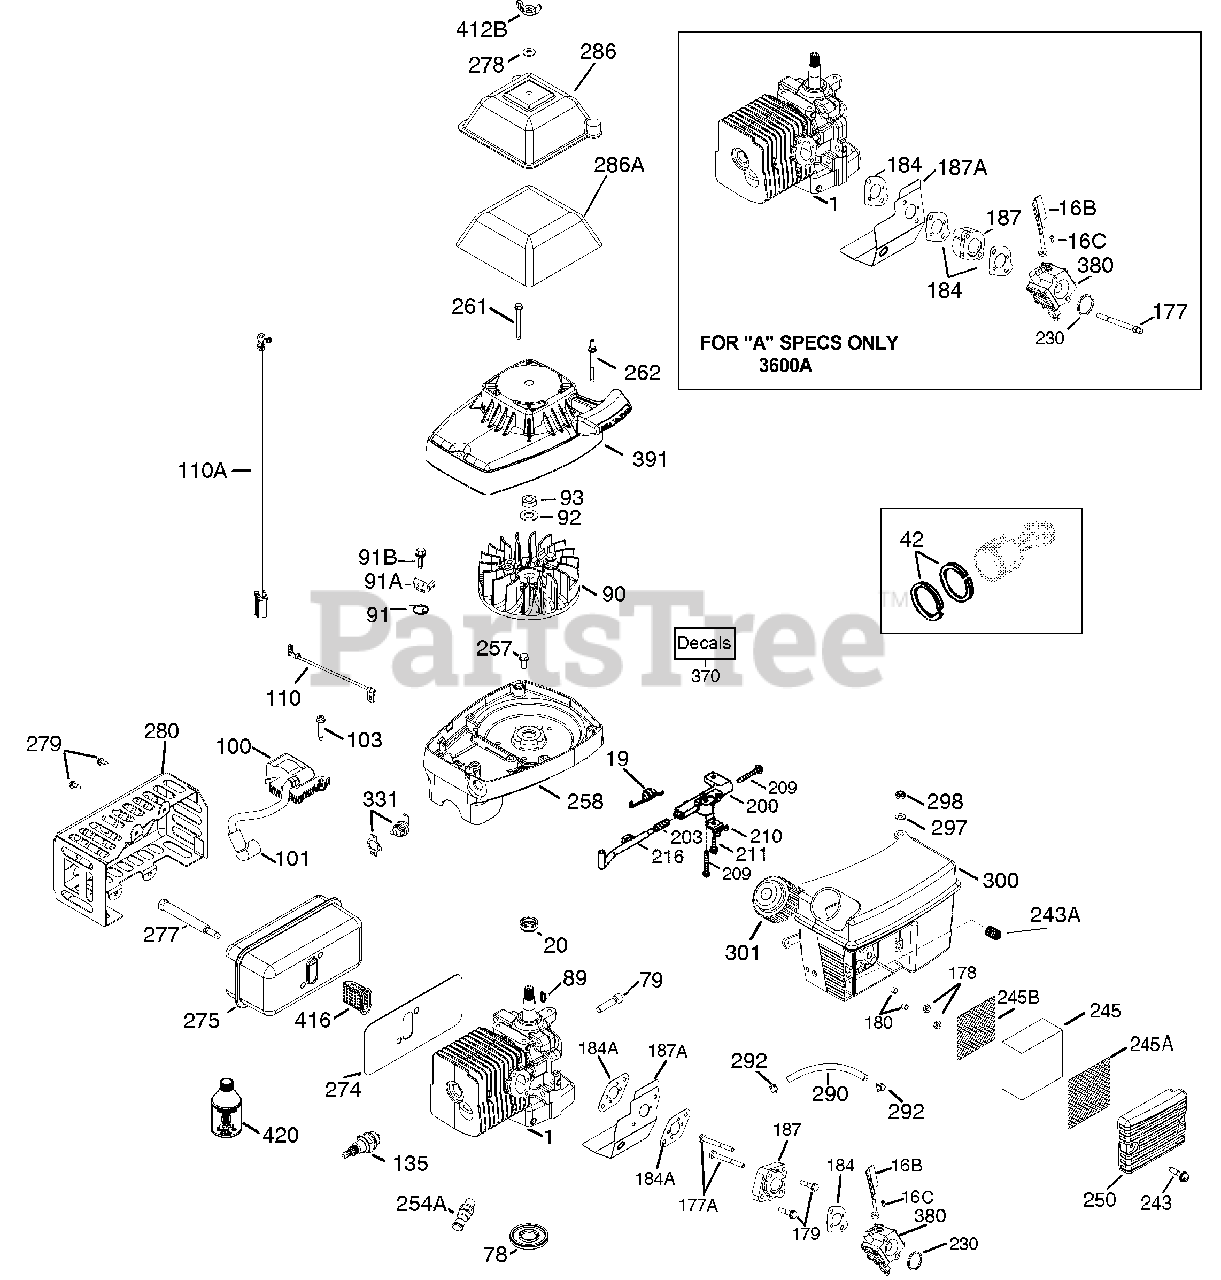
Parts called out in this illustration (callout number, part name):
16B	"Air Vane
16C	Screw, T-8, 3-48 x 7/32"
19	Governor Spring
20	Oil Seal
42	Piston Ring Set (Std)
78	Oil Seal
79	Screw, 1/4-20 X 1"
89	Flywheel Key
90	Flywheel
91	Pawl Spring used in kit #590779
91A	Starter Pawl used in kit #590779
91B	Shoulder Screw, 10-24 X 5/8" used in kit #590779
92	Belleville Washer
93	Flywheel Nut
100	Solid State Ignition (Incl. 101)
103	Screw, Torx T-15, 10-24 x 1"
110	Ground Wire
135	Resistor Spark Plug (RCJ6Y)
177A	SCREW CARB
178	Lock Nut, 10-24
179	SCREW SPACER
180	SPACER FUEL TANK
184	Carburetor Gasket
184A	Carburetor Gasket
187	SPACER CARBURETOR
187A	BAFFLE CARBURETOR
200	Speed Control Body
203	Compression Spring
209	Screw, 8-32 x 1"
210	Conduit Clip
211	Screw, T-15, 10-24 x 21/32"
216	R.P.M. Adjusting Lever
230	"O" Ring
243	Screw, 10-32 x 29/32"
243A	Threaded Insert (use for stripped hol es)
245	Air Filter (Poly) (also available in (incl. 450255 & 450257))
245A	Air Filter also available in Packaged Part #740097
245B	Air Filter (Flocked Screen)
250	Air Cleaner Cover
254A	Compression Relief Valve
257	Screw, 10-24 x 1/2"
258	Housing Base
261	Screw, 8-32 x 1-9/16"
274	Muffler Gasket
275	Muffler (Inc. 274 & 277)
277	Muffler Shoulder Screw
279	Screw, 8-32 x 25/64"
280	Heat Shield
290	Fuel Line
292	Fuel Line Clamp
298	Lock Nut, 8-32
300	Fuel Tank (Incl. 290, 292, 298, 301 &
301	Fuel Cap
331	Toggle Switch
355	Starter Handle
370	Caution Decal
370	Choke Decal
370	Starting Instructions Decal
380	Carburetor (incl. 184)
391	Recoil Starter & Housing Assy. Painte d Black composite
412B	Wing Nut, 10-24
416	Spark Arrestor Kit
